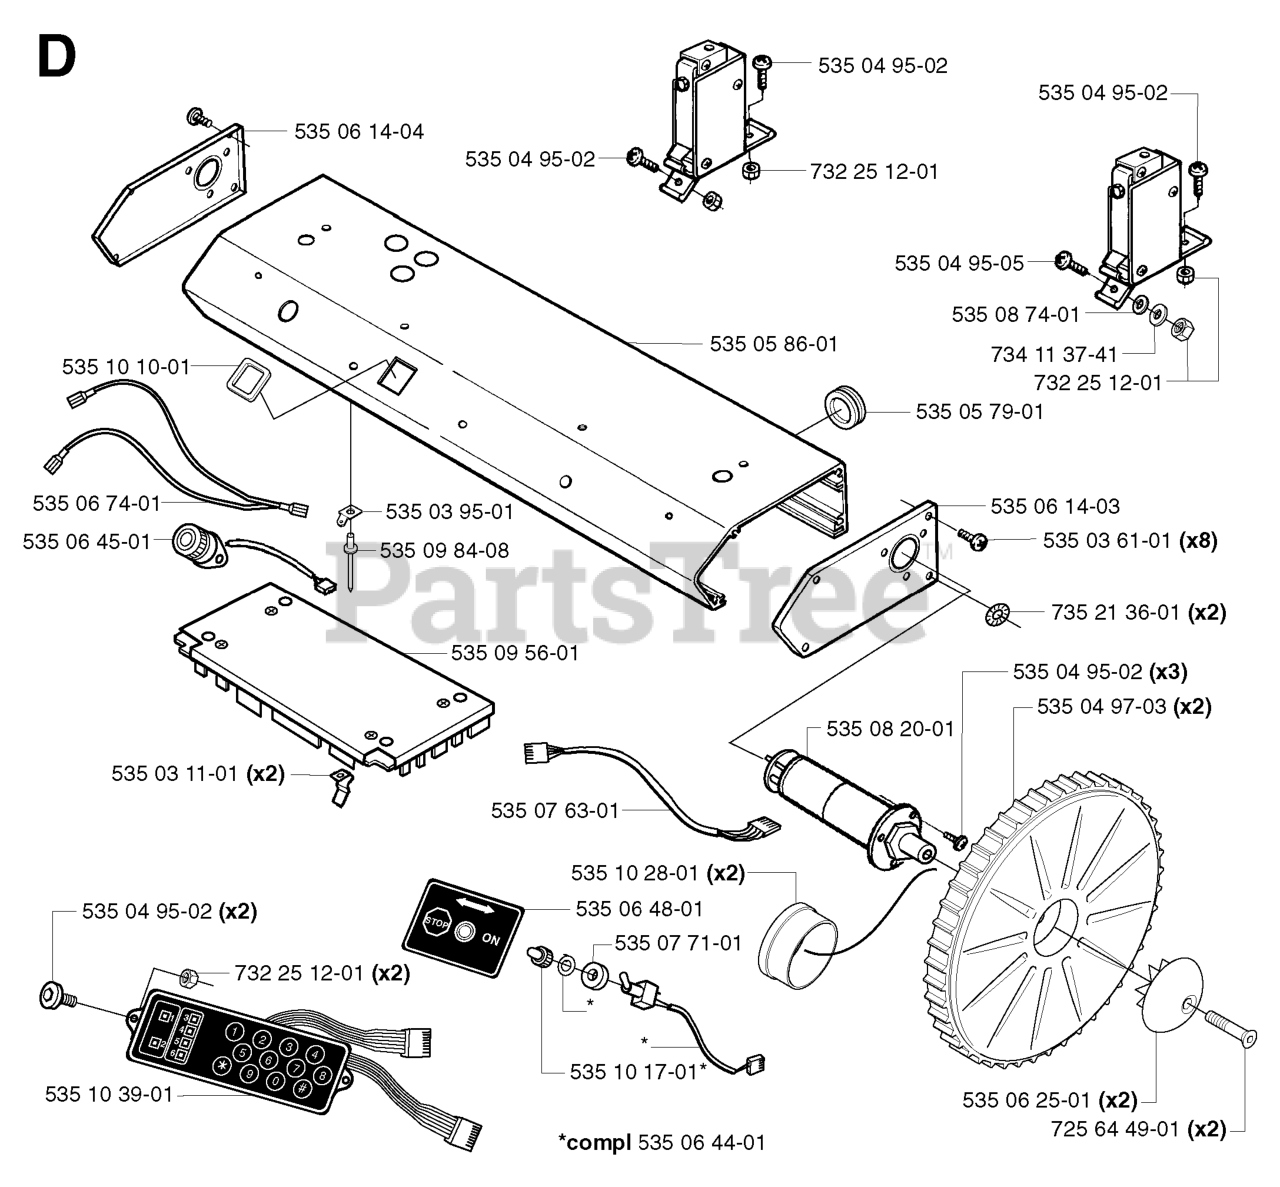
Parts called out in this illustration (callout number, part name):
2	DRAWBAR, GT
4	Nut, Crownlock Hex 7/16-14 unc
5	DASH.STEALTH.YTGT.2CYL.BLK
6	DASH VGT, LOWER
7	SCREW
8	SUPPORT, BATTERY
14	HOOD ASM.
15	LENS LH
16	COVER ACCESS
17	SCREW 3/8-16X3/4
18	GRILLE
19	WASHER
20	BOLT
21	NUT
24	FOOTREST RH
25	LENS RH
28	FOOT REST LH
30	SADDLE.HYDRO.95
31	BRACKET SUPT 1-PC VGT STEERING
34	PLATE ASM ENG CHASSIS
35	WASHER
36	SCREW 5/16"
39	BRACKET AXLE, FRONT
42	BOLT D
43	FRONT SUSPENSION BRKT LH
44	FRONT SUSPENSION BRKT RH
45	BRACKET SUSP RH
50	BRACKET, CHASSIS FRONT
56	BRACKET ASM, SUSP CHASSIS
58	BRACKET ASM, FENDER
68	Screw 5/16-18 x 1/2 Hex, Self Tapping 5/16-18 x 1/2
84	MOWER STOP
86	BOLT
99	ROD ASM, BYPASS
122	SCREW.HEX.WS.HD.8-18 X 7/8
130	SCREW
139	BOLT, SHOULDER 5/16-18
140	MAGNET STEALTH
141	STRIKER PLATE
142	BRACKET DASH STEALTH(R)
143	SKIRT GRILLE RH
144	BRACKET DASH STEALTH LH
146	SKIRT GRILLE LH
148	EXTRUSION BUMPER (3 2) (2 2)
150	DUCT HEAT HOOD
152	BROWNING SHIELD
158	SCREW 3/8-16X1/2
160	SCREW 5/16-18X1/2"
